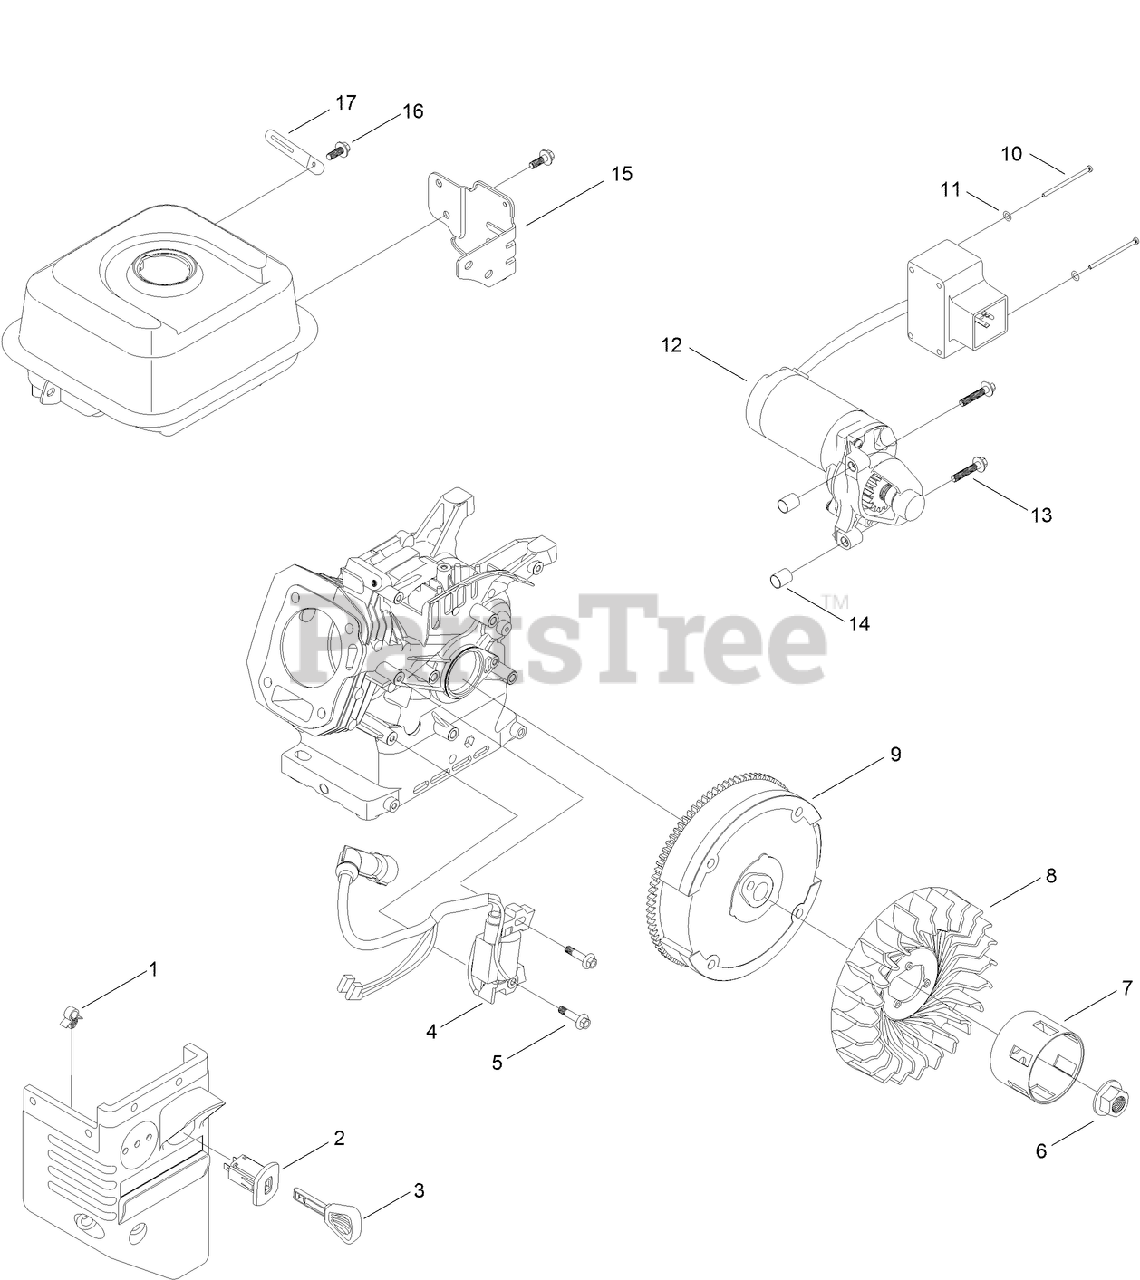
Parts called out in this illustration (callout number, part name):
2	SWITCH-KEY
5	SCREW-HHF
6	NUT-FLANGE
7	CUP-STARTER
9	FLYWHEEL
10	SCREW-BHP
11	WASHER-PLAIN
13	SCREW-HHF
14	PIN-DOWEL
15	BRACKET-BOX, SWITCH
16	SCREW-HHF
17	CLIP-HARNESS, WIRE
